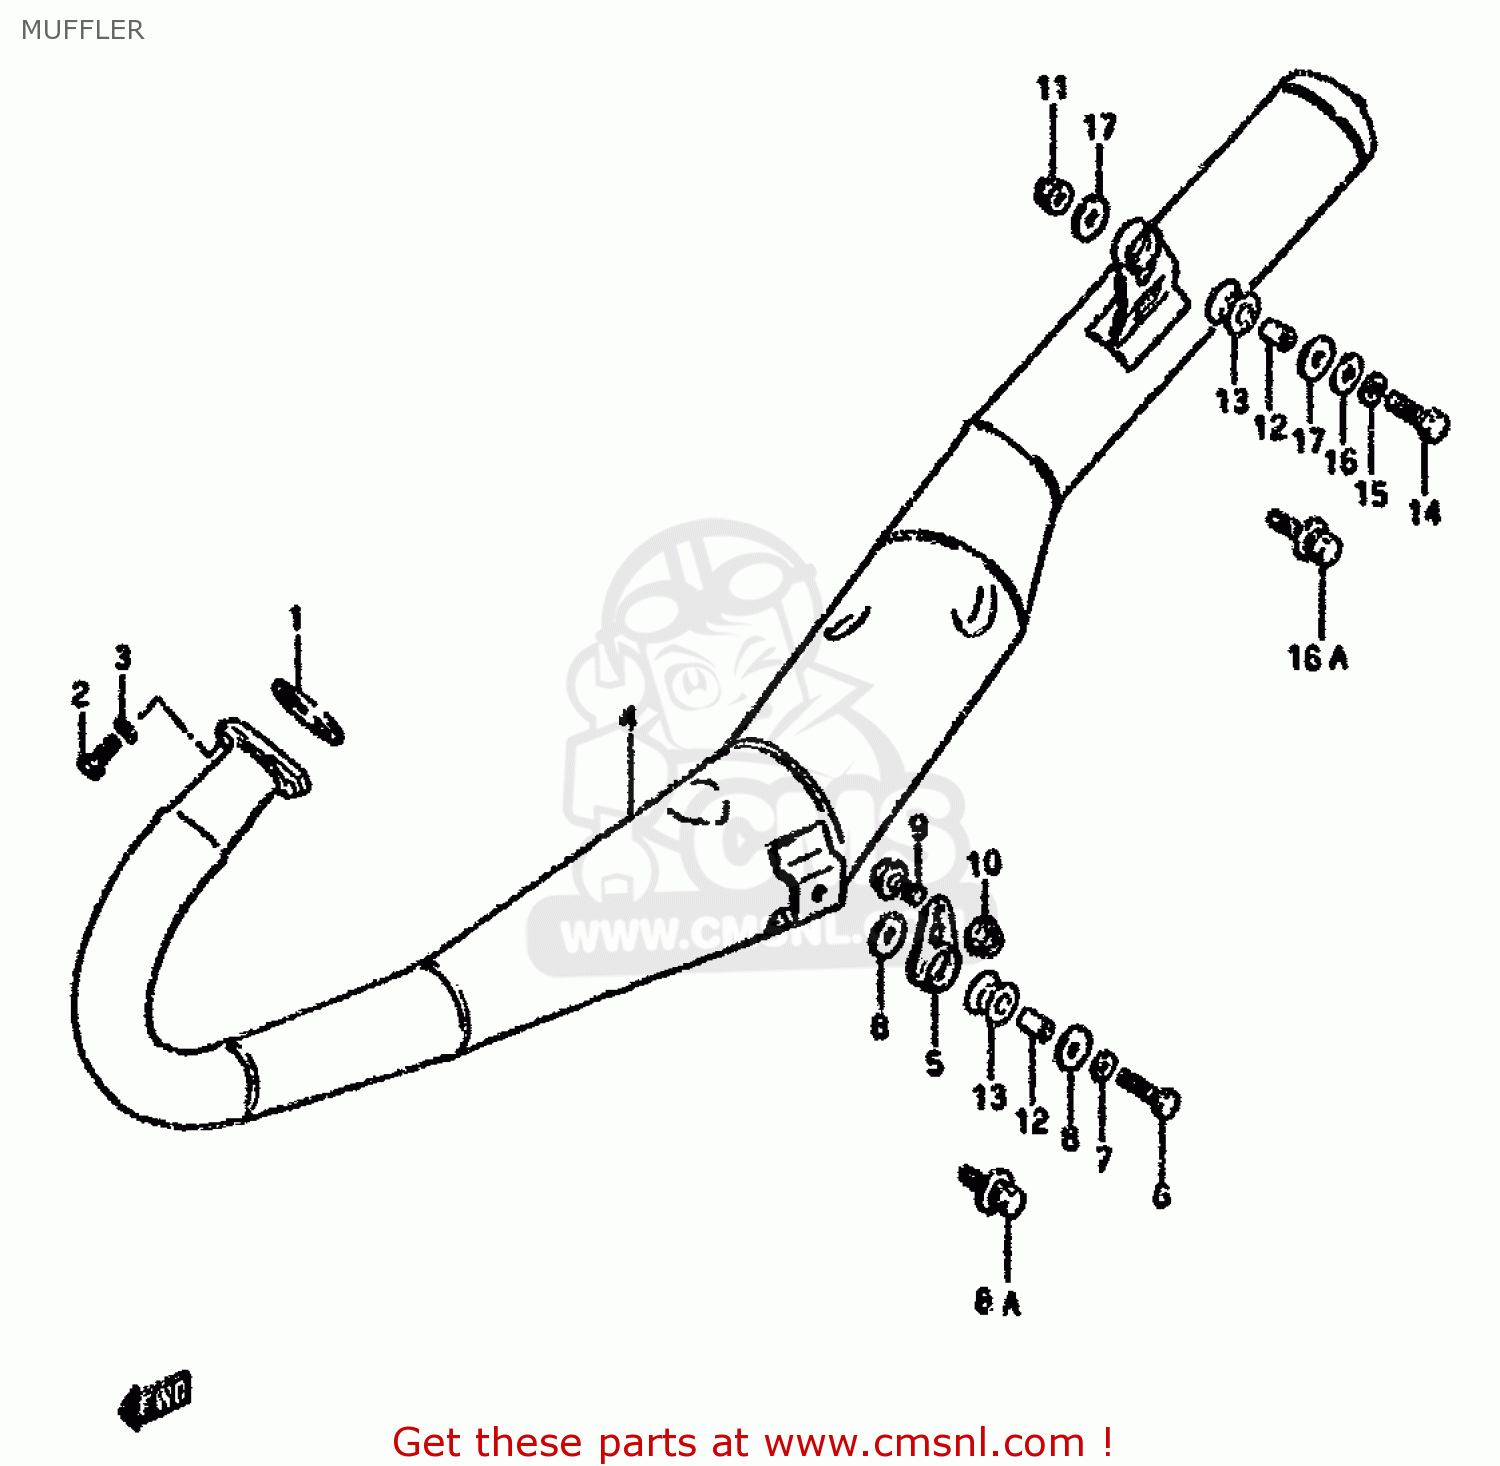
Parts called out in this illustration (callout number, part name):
1	GASKET,EXHAUST (NAS)
2	BOLT
3	WASHER,LOCK
3A	BOLT
4	MUFFLER ASSY
5	DAMPER
6	BOLT
7	WASHER,LOCK,8.
8	WASHER (8.5X20X1.6)
8A	BOLT(8X35)
9	BOLT
10	NUT
11	NUT
12	SPACER(8.6X12X17.5)
13	CUSHION
14	BOLT 8X40
15	LOCK WASHER
16	WASHER (8.7X22X2)
16A	BOLT (8X40)
17	WASHER (8.5X29X1.6)
